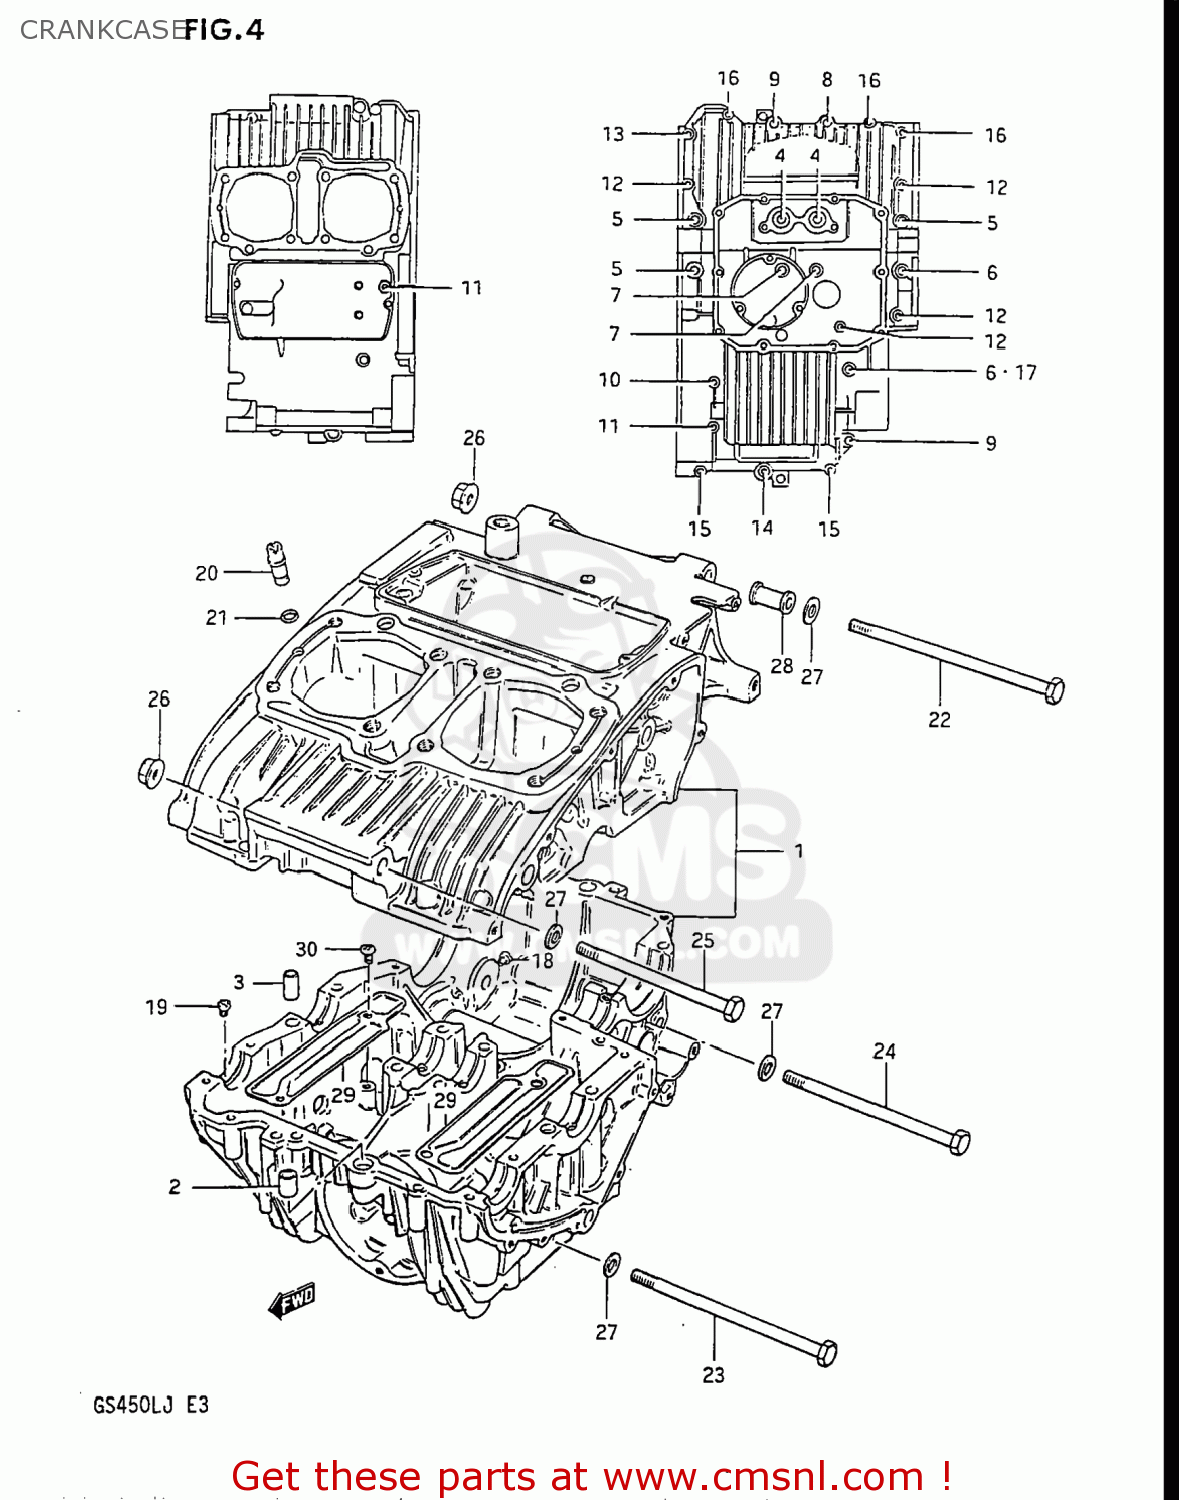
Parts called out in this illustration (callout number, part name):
1	CRANKCASE SET
2	PIN(10.4X13X22)
3	PIN (11X20)(SUS)
4	BOLT (8X70)
5	BOLT(8X125)
6	BOLT
7	BOLT(8X100)
8	BOLT (8X65)
9	BOLT
10	BOLT(6X125)
11	BOLT(6X105)
12	BOLT (6X90)
13	BOLT
14	BOLT
15	BOLT 6X50
16	BOLT (6X45)
17	GASKET 8.2X14X1 (NAS)
18	JET,AIR
19	JET
20	JET
21	O RING(D:1.05,ID:3.1)
22	BOLT
23	BOLT
24	BOLT
25	BOLT
26	NUT 10MM
27	WASHER 10MM
28	SPACER,ENGINE MOUNT
29	PLATE,OIL SEPARATOR
30	SCREW
